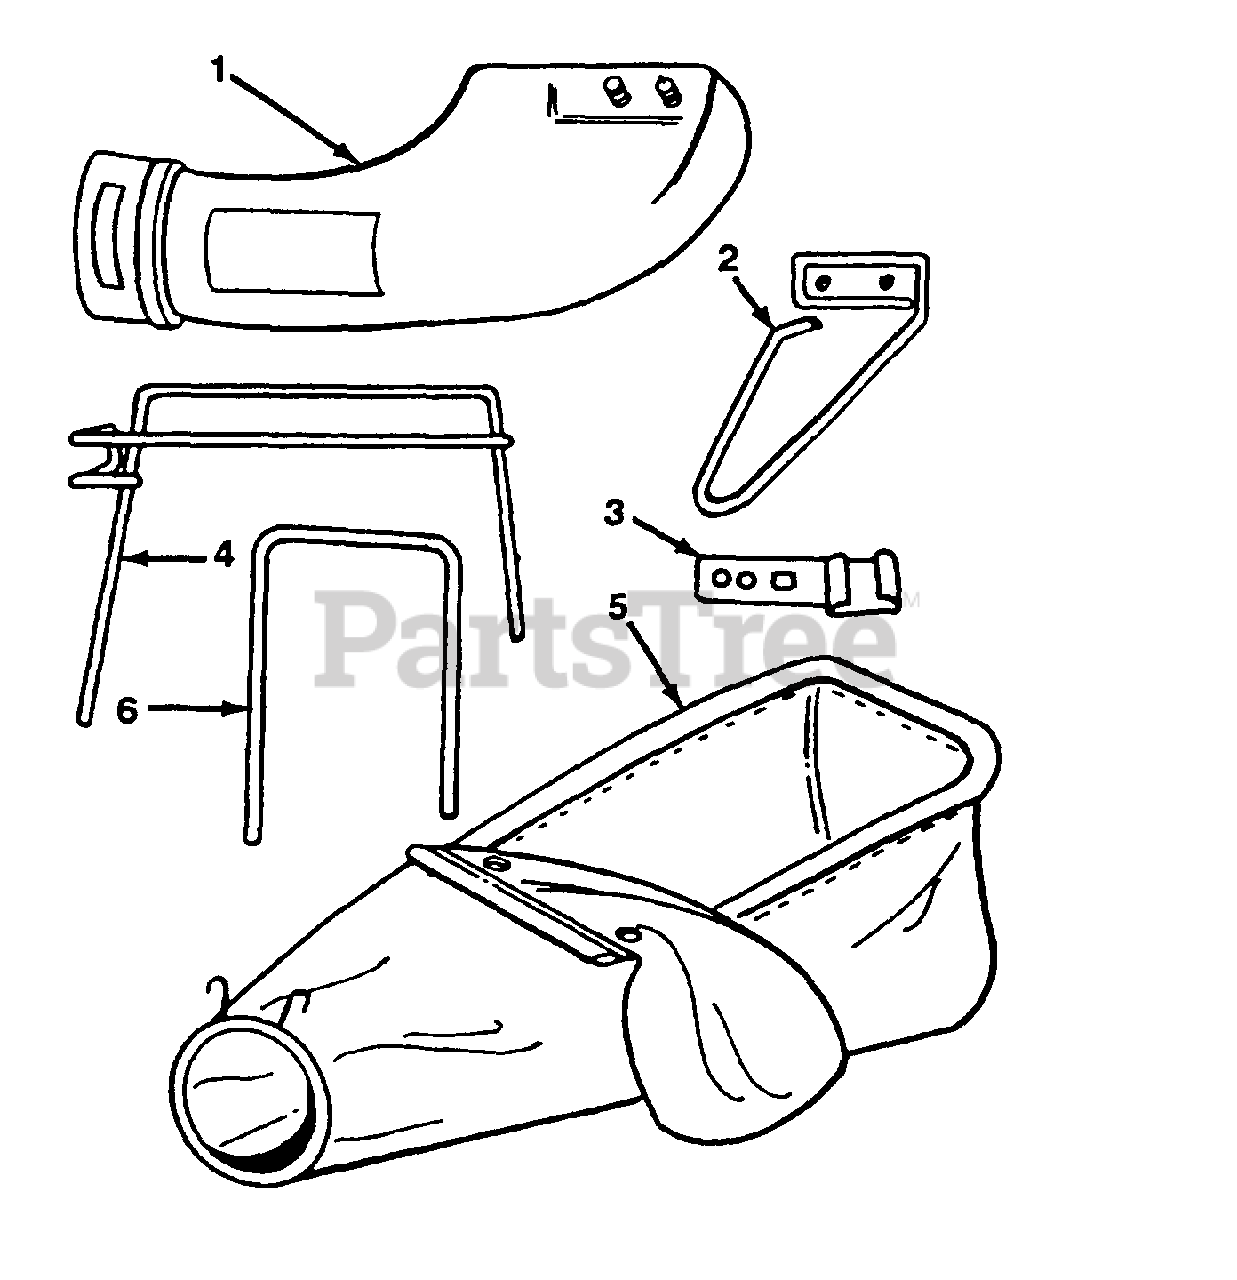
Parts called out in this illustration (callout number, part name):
1	Plastic Chute
2	Chute Mounting Bracket w/Wire
3	Handle Bracket
4	Bag Frame
5	Bag w/Clamp Ring
6	Upper Support
